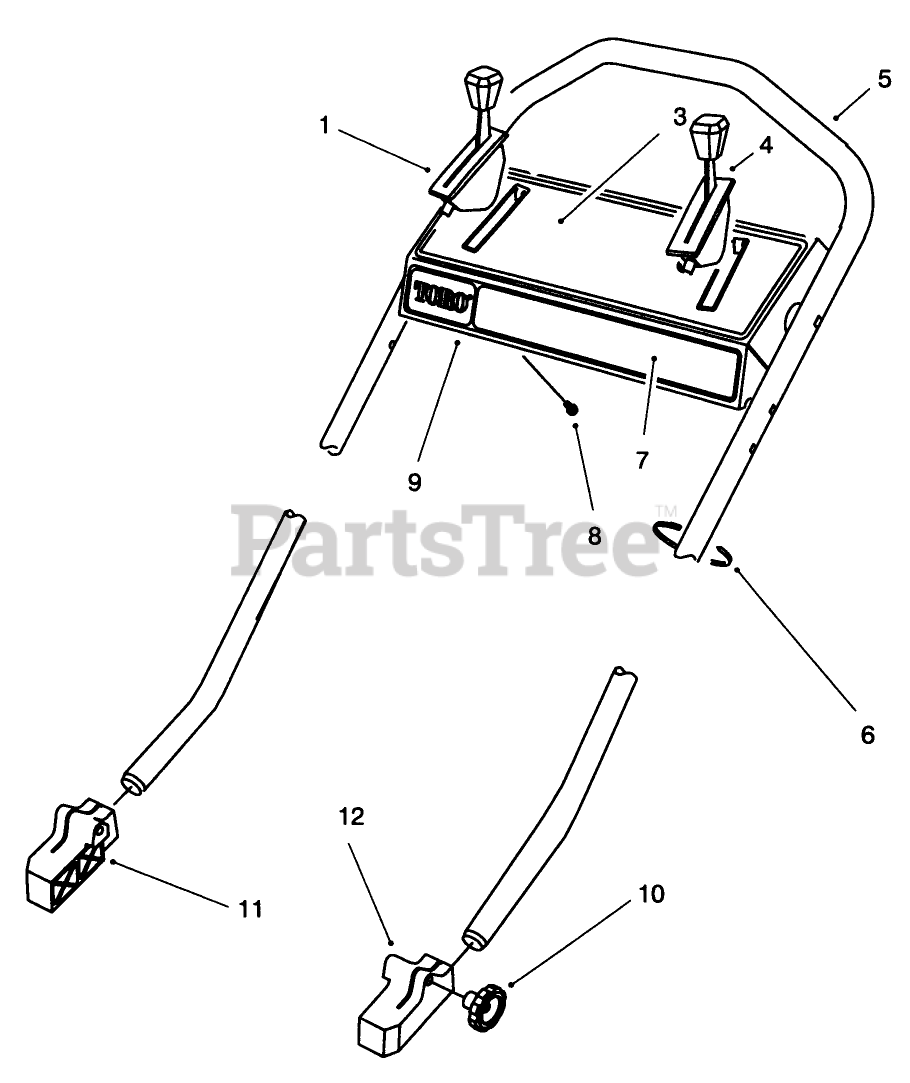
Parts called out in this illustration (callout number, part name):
1	CONTROL-SPEED, GROUND
3	DECAL - INSTRUCTION
4	CONTROL - THROTTLE
5	HANDLE
6	TIE-CABLE
7	DECAL-PANEL
8	SCREW-TAP
9	PANEL
11	MOUNT-HANDLE, RH
12	MOUNT-HANDLE, LH
